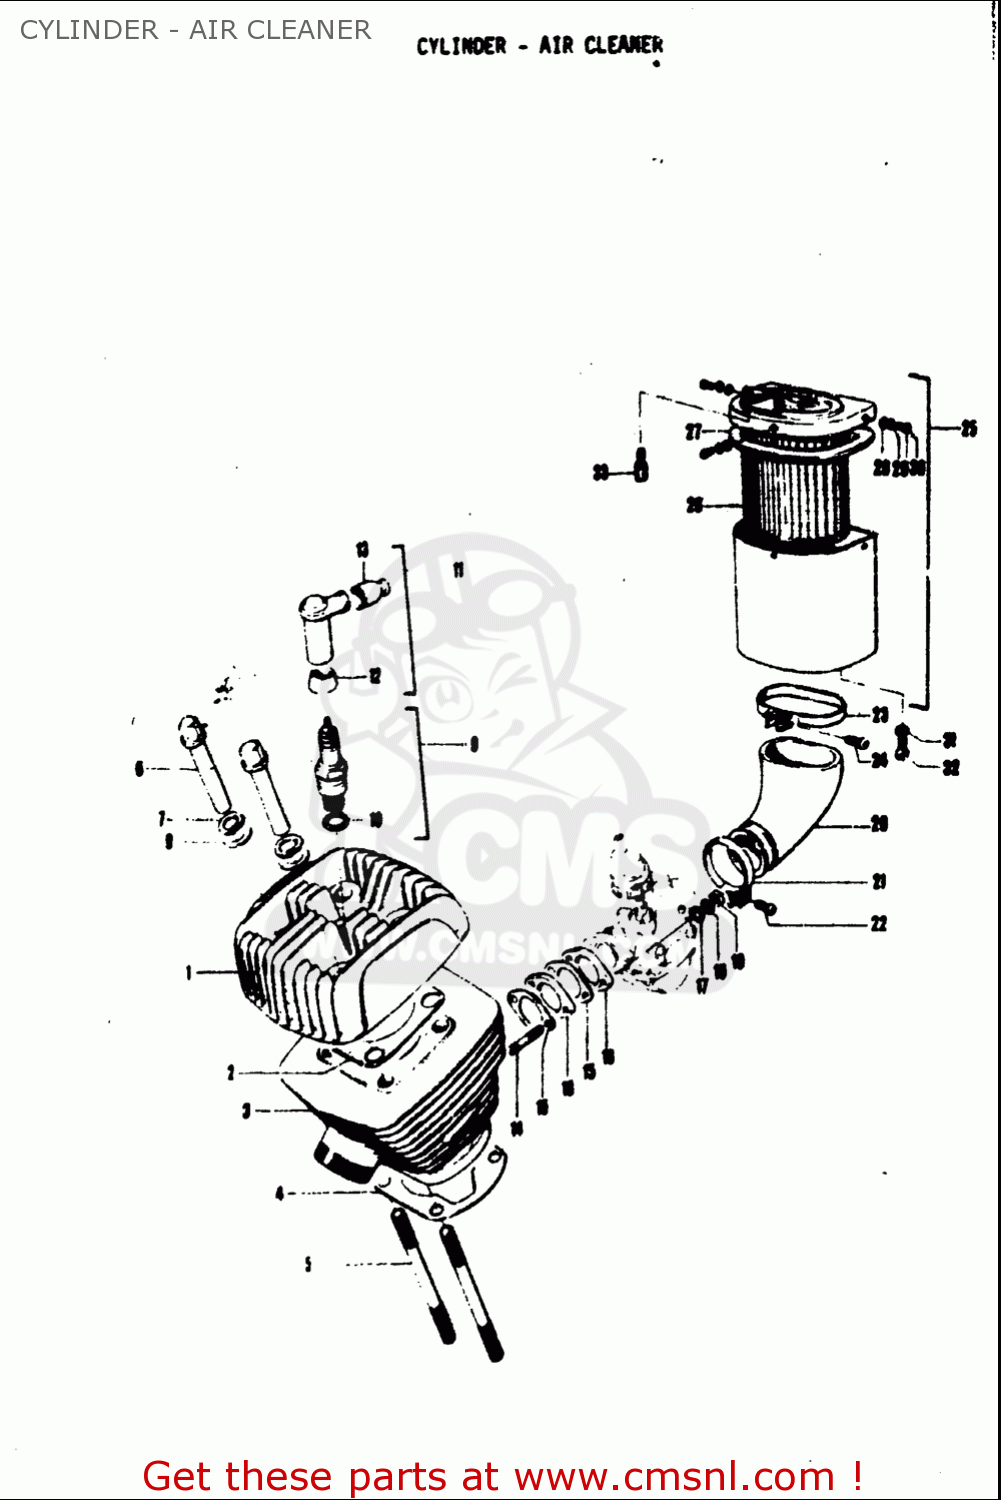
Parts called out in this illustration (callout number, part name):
1	HEAD,CYLINDER
2	GASKET,CYLINDER HEAD (A (NAS)
4	GASKET,CYLINDER (NAS)
6	NUT
7	WASHER,LOCK
8	WASHER
9	PLUG,SPARK(B7HS)
10	GASKET(14X19.2X2) (NAS)
14	STUD
15	GASKET,CARBURETOR (NAS)
16	INSULATOR,CABURETOR
17	WASHER
18	WASHER,LOCK
19	NUT
21	CLAMP
22	SCREW
24	SCREW
28	WASHER
29	WASHER,LOCK
31	WASHER,LOCK
